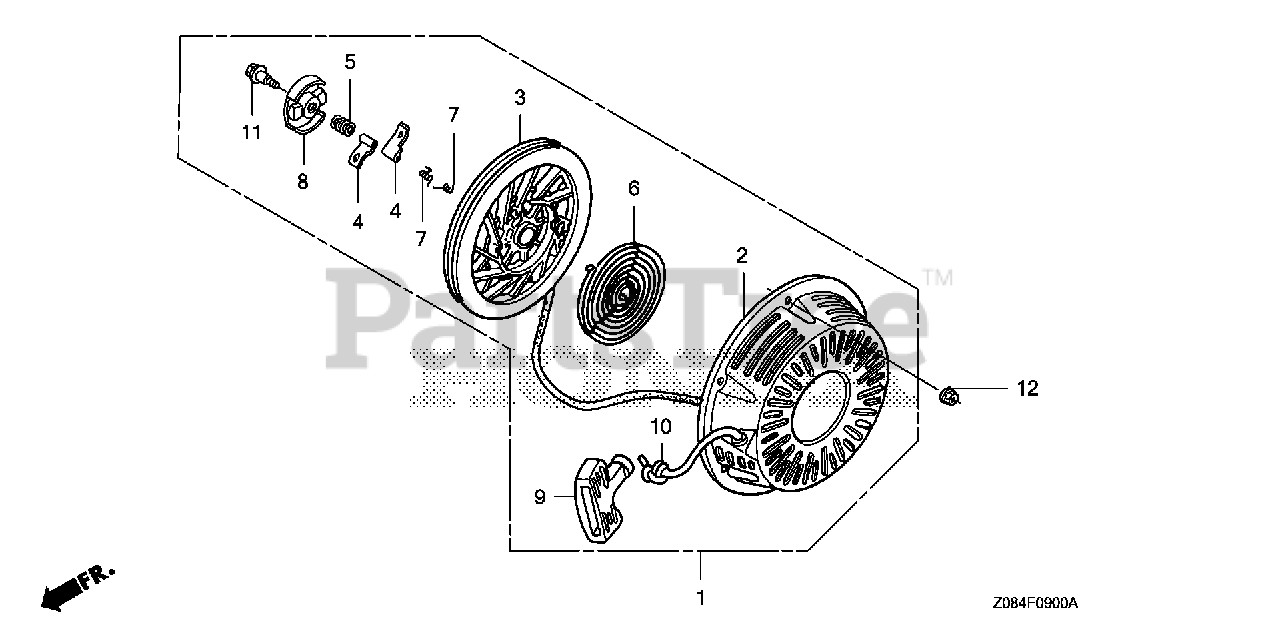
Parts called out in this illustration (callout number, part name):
1	STARTER ASSY., RECOIL *R280* (POWER RED)
2	CASE, RECOIL STARTER *R280* (POWER RED)
3	PULLEY, RECOIL STARTER
4	RATCHET, STARTER
5	SPRING, FRICTION
6	SPRING, STARTER RETURN
7	SPRING, RATCHET
8	RETAINER, SPRING
9	GRIP, STARTER
10	ROPE, RECOIL STARTER
11	SCREW, CENTER
12	NUT, FLANGE (6MM)
